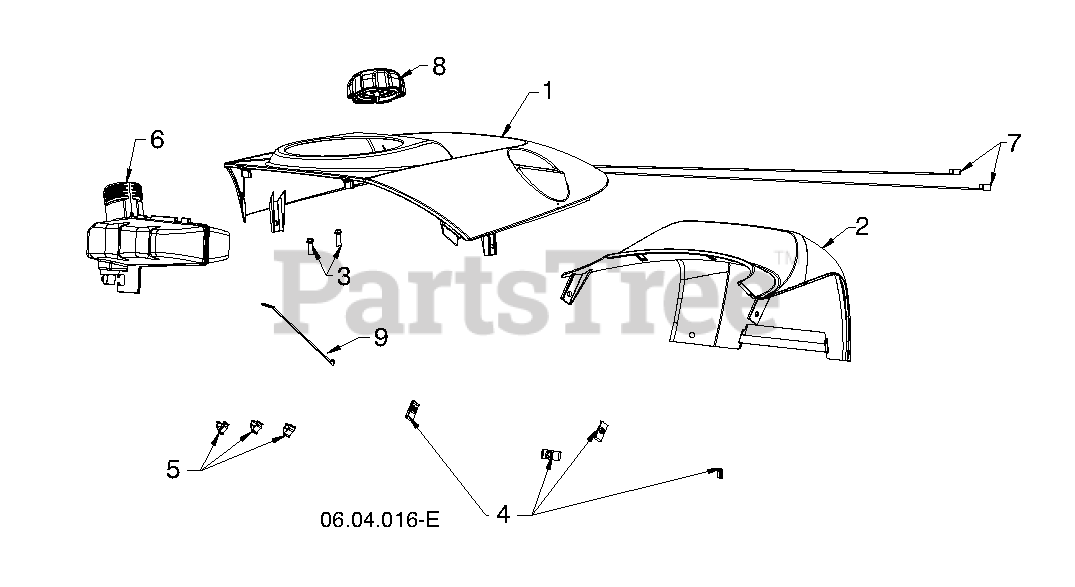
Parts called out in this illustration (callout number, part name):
1	COVER.TOP.SINGLE.STAGE.SNOW.BL
2	TOP.REAR.COVER
3	SCREW.HX.13X.750
6	TANK.GAS.12.SINGLE.STAGE.SNOW
7	TIE.CABLE.24.5X.29.NYLON.WHITE
8	CAP.2.25'.VENTED.RATCHET.EPA
